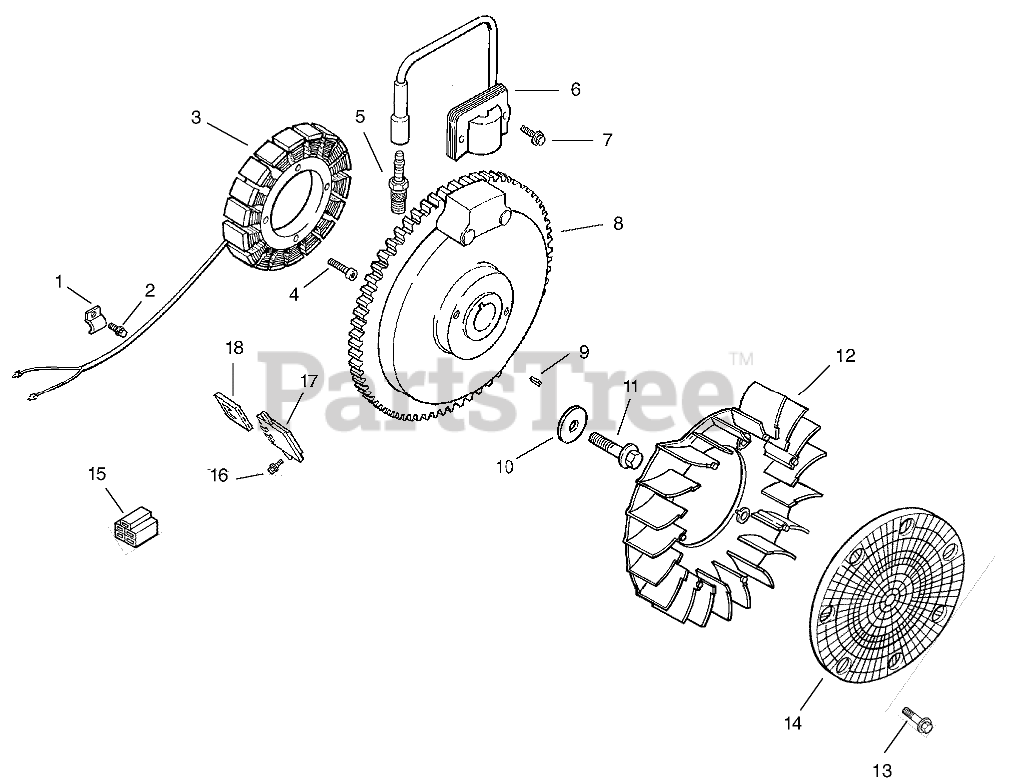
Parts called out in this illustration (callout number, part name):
2	SCREW-HHFTF (M5X.80X10)
3	Kit, stator-15 amp (Includes Terminal 25 452 01 qty. 2])
4	SCREW-THREAD FORMING (M5X0.8X25)
5	SPARK PLUG
6	Module-Ignition
7	SCREW-FLANGE, THREAD FORMING (M5X.8X20)
8	Flywheel
9	KEY (3/16 X 5/8)
10	WASHER-FLAT (13/32)
11	SCREW-FLANGE (M10X1.5X45)
13	BOLT-SHOULDER (M6x1.0x16)
14	Screen-Grass
15	Connector (5 contact)
16	Screw-HF (M6x1.0x16)
17	Rectifier-Regulator
18	Connector (3 contact)
